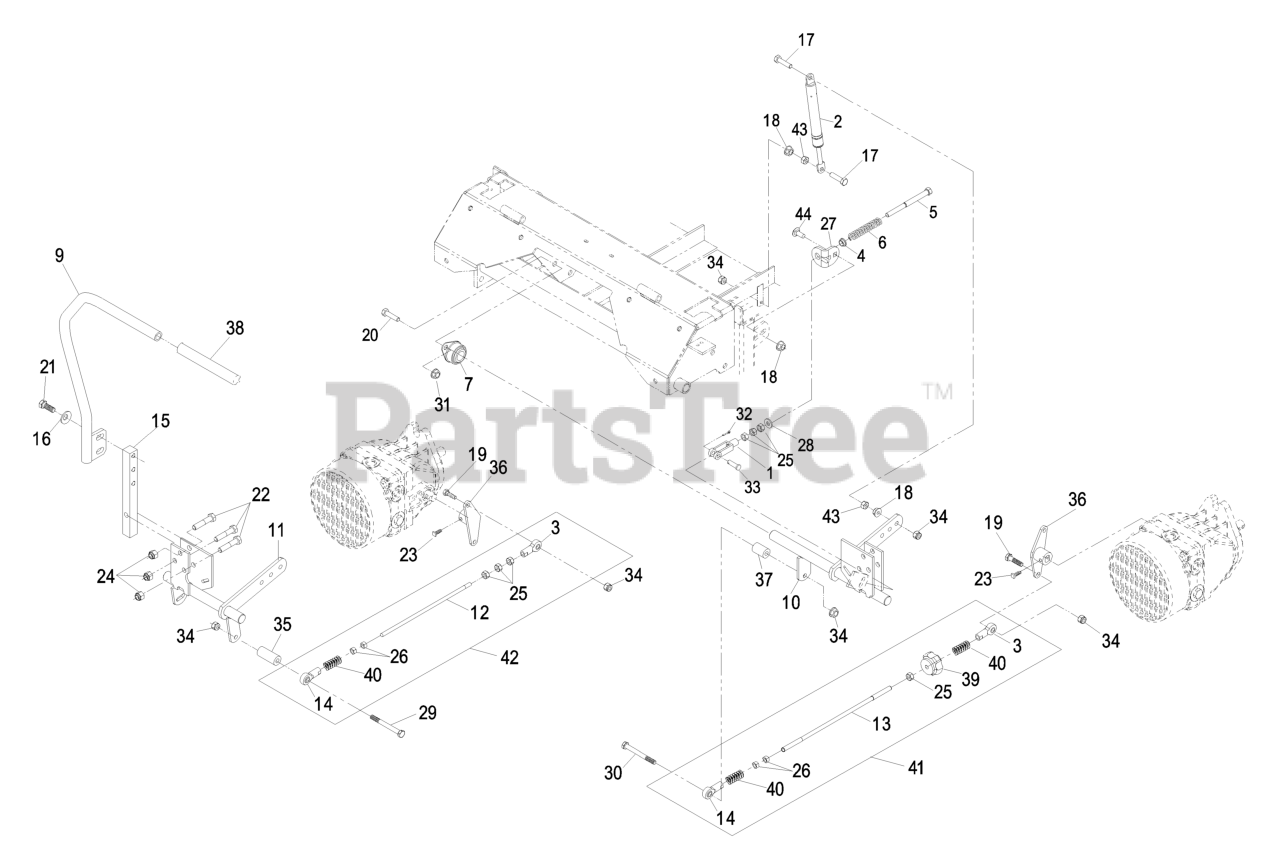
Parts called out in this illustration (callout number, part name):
1	YOKE-ADJUSTABLE
2	DAMPER-CONTROL, MOTION
3	BALLJOINT-RH
4	BUSHING-NYLON, FLANGED
5	BOLT-RETURN, NEUTRAL
6	SPRING-RETURN, NEUTRAL
7	BEARING-FLANGE, SIDE
9	ASM.RH LEVER/GRIP
11	CONTROL-MOTION, RH
12	LINK,XP HYDRO CONNECT RH
13	LINK,TRACKING ROD XP
14	BALLJOINT-LH
15	ARM-SHAFT, CONTROL
16	WASHER-BELLEVILLE
17	SCREW-HH
19	SCREW-HH
20	SCREW-HH
21	SCREW-HH
22	SCREW-HH
23	SCREW-SET
24	NUT-LOCK, NI
25	NUT-HEX
27	TAB-ADJUSTMENT
28	WASHER-FLAT
29	SCREW-HH
30	SCREW-HH
31	NUT-HHF, WHIZ
32	PIN-COTTER
33	PIN-CLEVIS
34	NUT-LOCK, NI
35	SPACER-CONTROL, HYD
36	ARM-CONTROL, HYDRO
37	SPACER-HYDRO CONTROL, LH
38	GRIP,CONTROL LEVER
39	KNOB-TRACKING
40	SPRING-COMPRESSION
41	TRACKING ROD ASM
42	RH HYD CONNECT LINK ASM
43	NUT-HEX
44	SCREW-CARR
